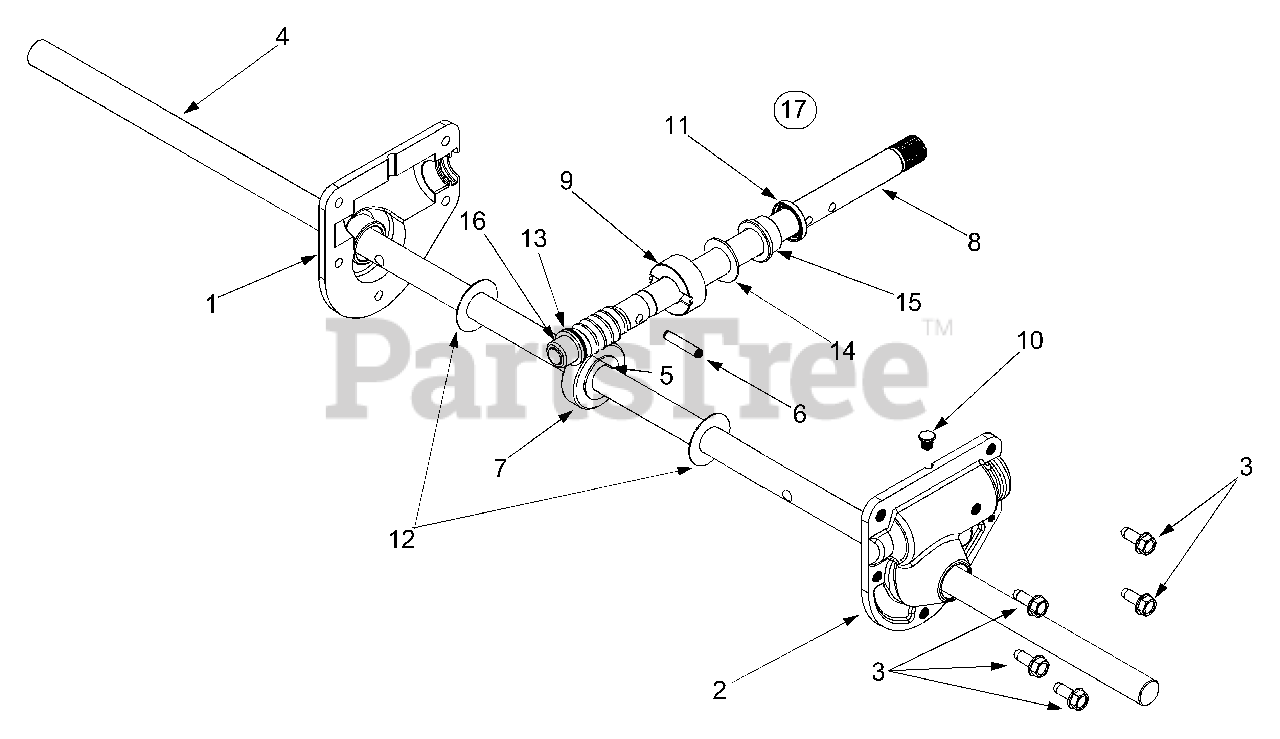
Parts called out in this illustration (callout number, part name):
1	RH Housing
2	LH Housing
3	Self Tapping Screw, 1/4-20 x .75
4	Spiral Axle 28"
5	Hi-Pro Key, 3/16 x 5/8
6	Spring Spiral Pin, .25 x 1.25
7	Worm Gear, 20-tooth
8	Worm Shaft
9	Thrust Collar
10	Grease Plug
11	Grease Seal
12	Flat Washer, .76 x 1.5 x .030
13	Flat Washer, .508 x 1.0 x .020
14	Flat Washer, .76 x 1.5 x .060
15	Flange Bearing, .75 x 1.0 x .59
16	Flange Bearing, .503 ID x .75 OD
17	Gear Assembly Complete, 28"
